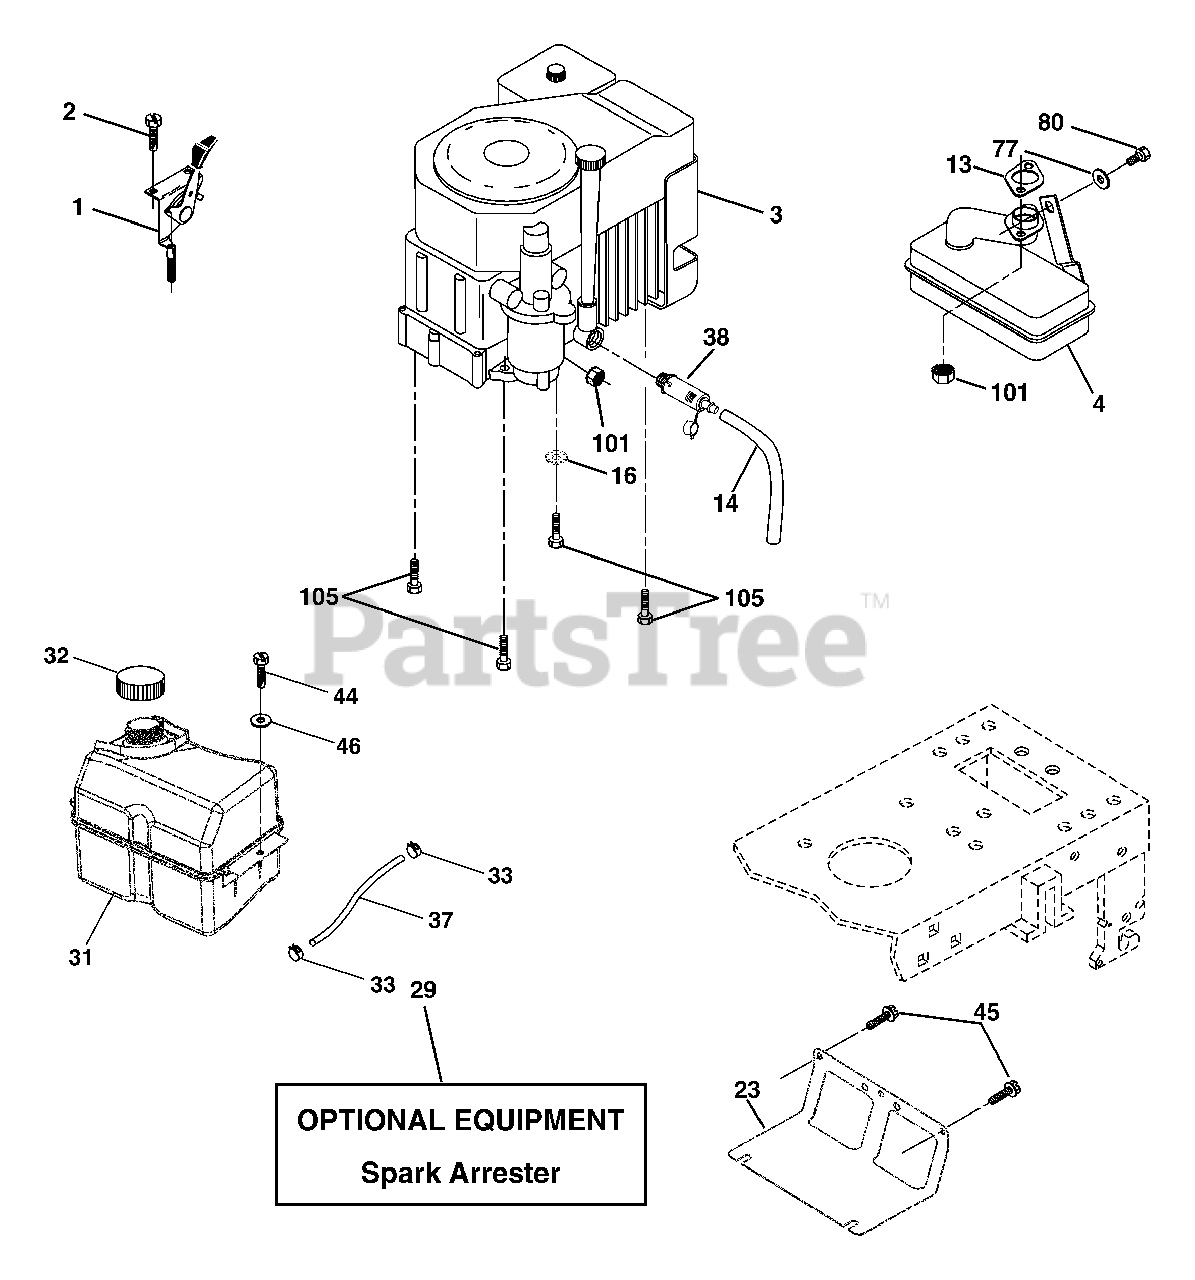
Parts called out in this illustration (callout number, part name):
1	Control Throt /Ch Flag
2	Screw Hex Thd Cut 1/4-20x1/2
4	Muffler Exhaust
14	Tube Drain Oil Easy
16	Washer Lock Ext Tooth 3/8
23	Shield Browning/Debris Guard
29	Arrestor Spark
31	Tank Fuel
32	Cap Asm Fuel W/sym Vented
33	Clamp Hose Blk
37	Line Fuel 20"
38	Plug Drain Oil Easy
44	Screw Hexwsh Thdrol 1/4-20x3/4
45	Screw Hex Wsh Thdrol 3/8-16
46	Washer 9/32 X 7/8 X 16ga
77	Washer 5/16 x 3/4 x 16 Ga.
80	Bolt Hex Hd 5/16-18 Unc x 1/2
101	Nut Flange
105	Screw 3/8-16 x 1
